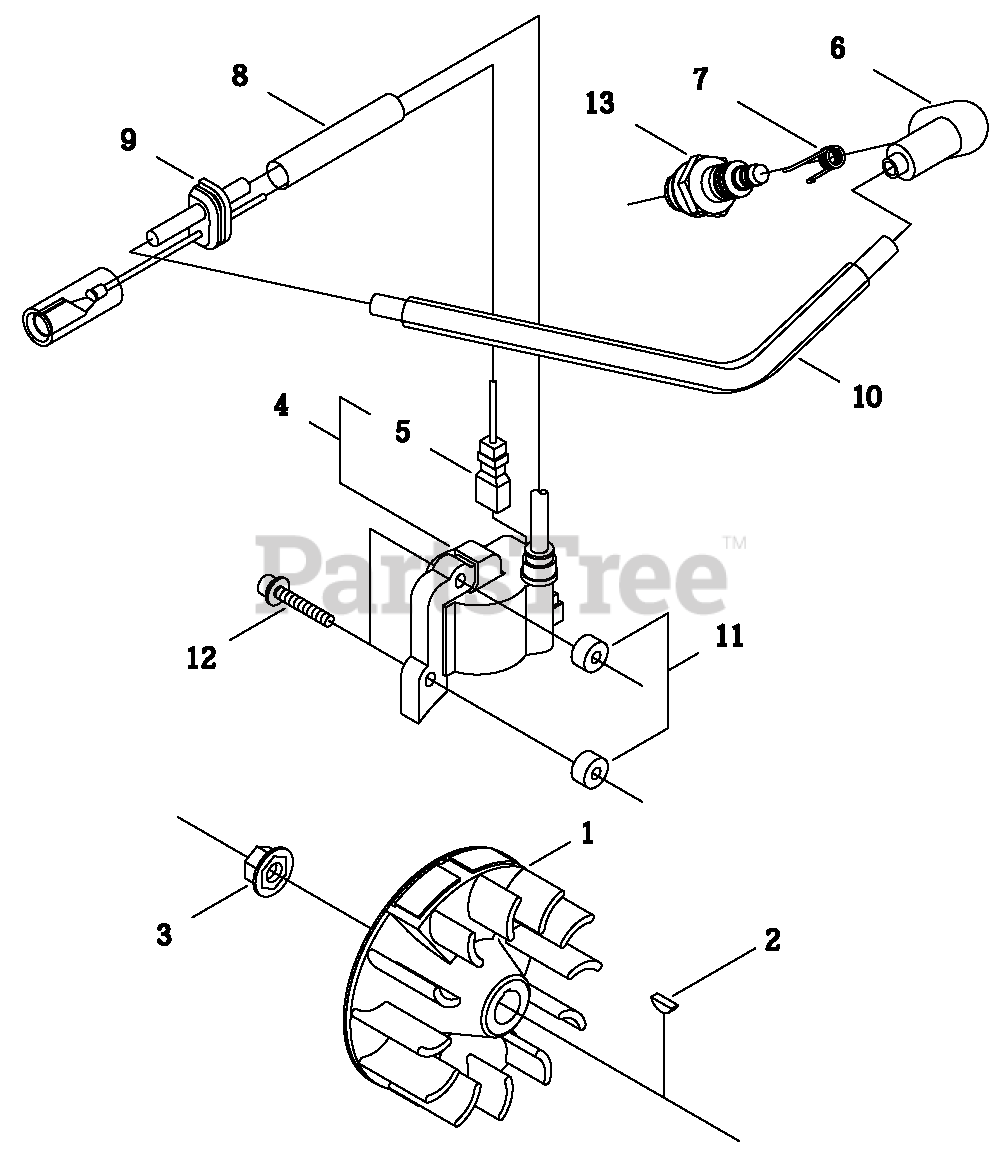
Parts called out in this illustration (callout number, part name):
1	FLYWHEEL
2	KEY - 3X10
3	NUT - 8
4	IGNITION COIL ASSY
5	WIRE
6	CAP, SPARK PLUG
7	TERMINAL, SPARK PLUG CAP
8	TUBE, INSULATOR
9	GROMMET
10	TUBE
11	INSULATOR
12	SCREW - 4X26
13	SPARK PLUG -- CJ-8
